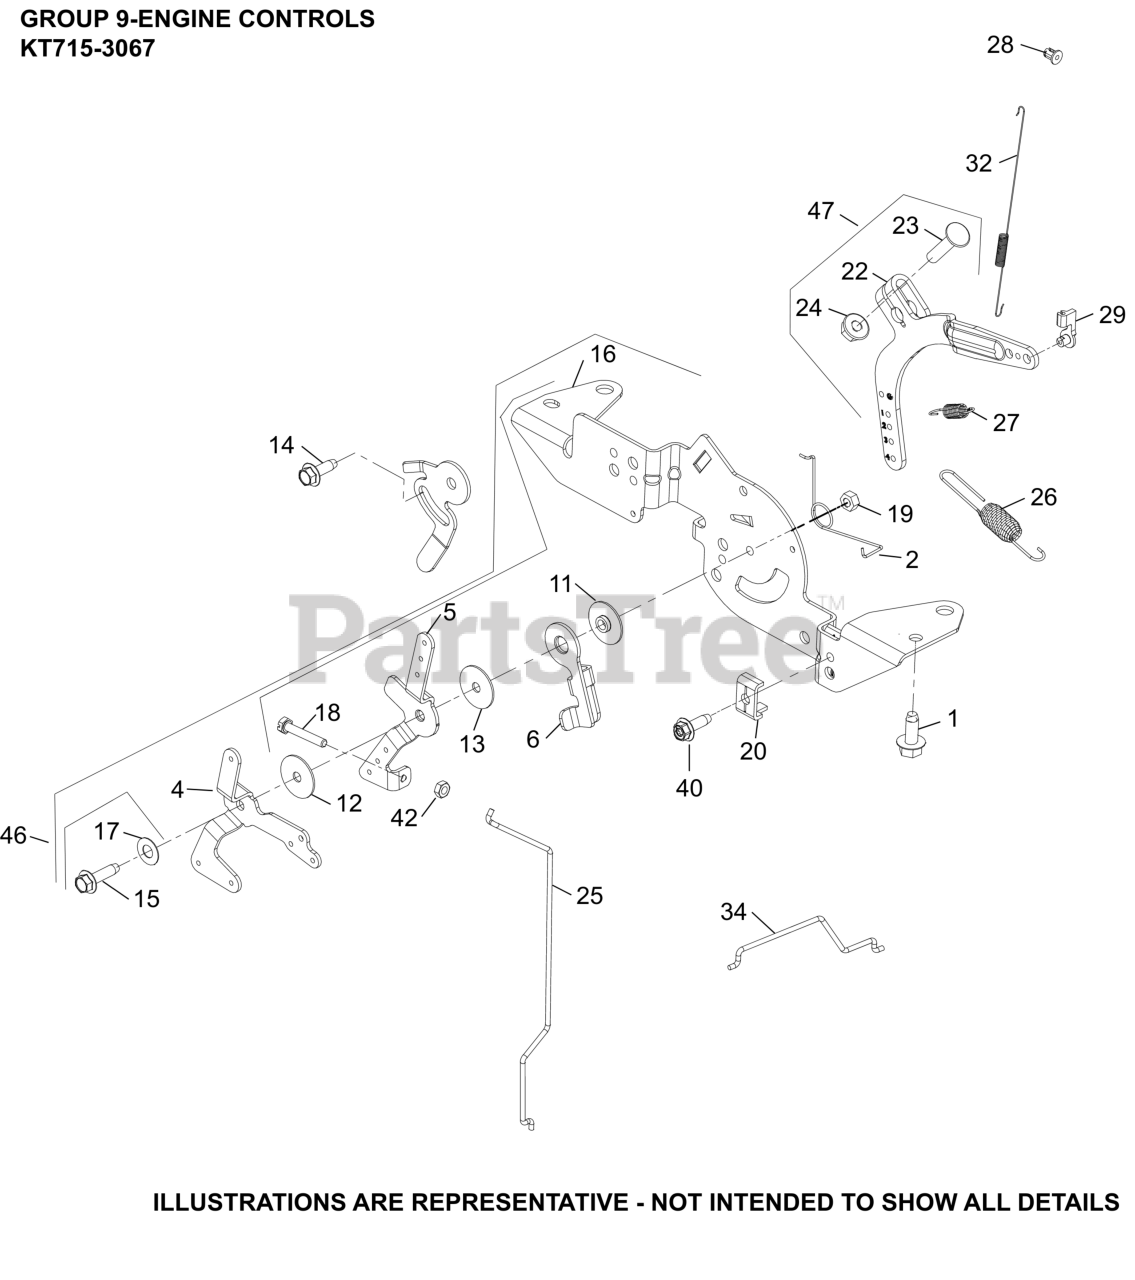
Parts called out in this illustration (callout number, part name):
1	SCREW, THREAD FORMING
2	SPRING, CHOKE RETURN
4	LEVER, CHOKE
5	LEVER, THROTTLE CONTROL
6	LEVER, THROTTLE ACTUATOR
11	SPACER, CONTROL ASSEMBLY
12	WASHER, FLAT 5.5 MM
13	WASHER, FLAT 5 MM
14	SCREW, THREAD FORMING
15	SCREW, THD FRM-USE 25 086 473-S
16	BRACKET, SPEED CONTROL
17	WASHER, SPRING 1/4"
18	SCREW, SLT HD CAP M4X0.7X25
19	NUT, LOCK M5X.8
20	CLAMP, CABLE CABLE
22	LEVER, GOVERNOR - (#2409069S)
23	BOLT, RD HD SQ NECK M6X1.0X25
24	NUT, FLG M6X1.0
25	LINKAGE, CHOKE
26	SPRING, GOVERNOR (PURPLE)
27	SPRING, GOVERNED IDLE
28	BUSHING, LINKAGE RETAINING
29	BUSHING, THROTTLE LINKAGE
32	SPRING, LINKAGE
34	LINKAGE, THROTTLE
40	SCREW, THREAD FORMING
42	NUT, M4X0.7
46	CONTROL ASSEMBLY, DUAL WIRE
47	LEVER, GOVERNOR ASSEMBLY
